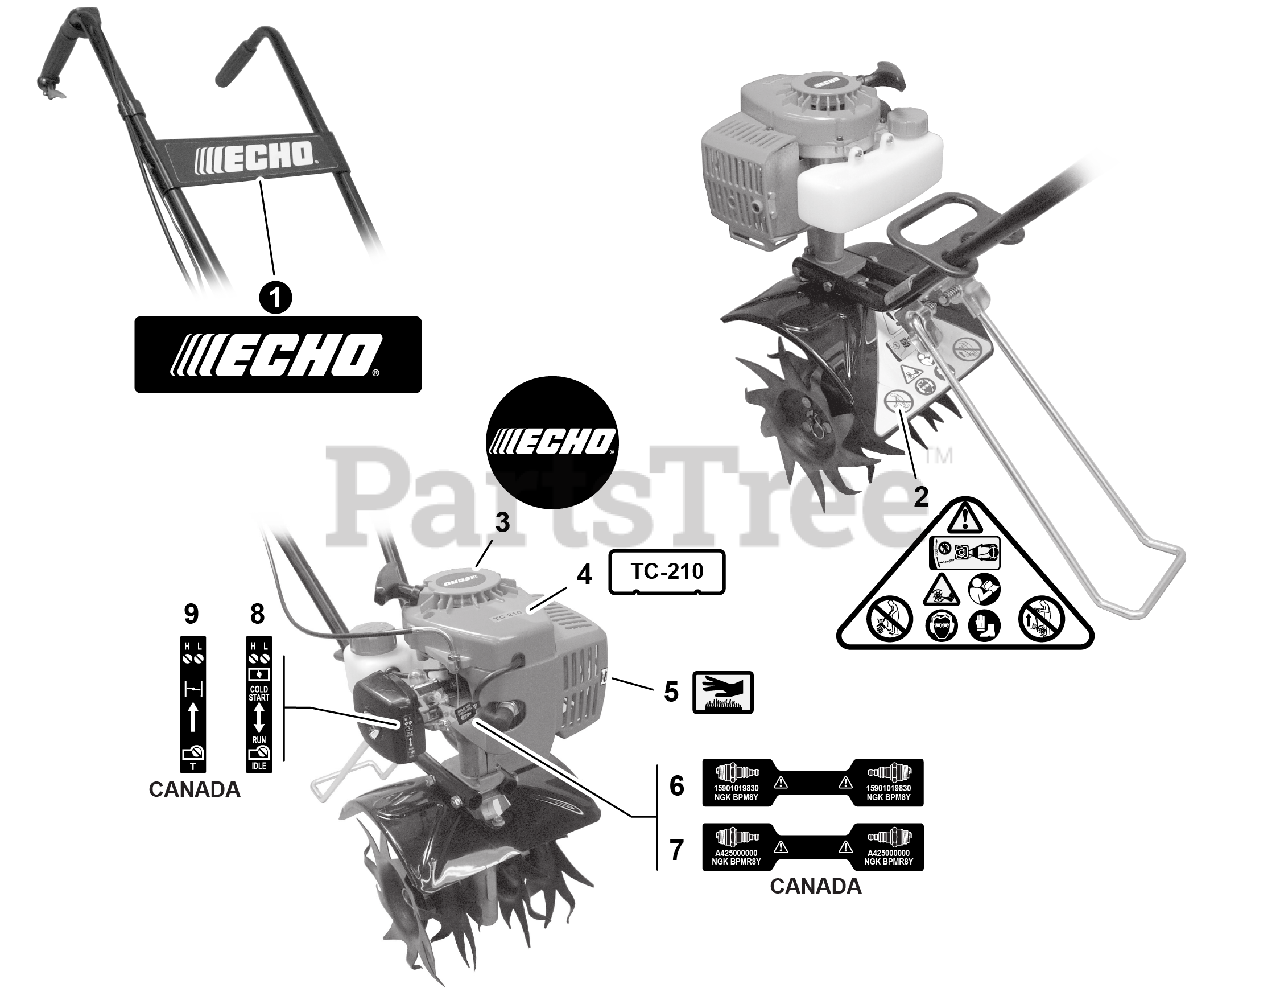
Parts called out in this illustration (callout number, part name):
1	LABEL, ECHO
2	LABEL, CAUTION
3	LABEL, ECHO
4	LABEL, MODEL
5	LABEL, CAUTION - HOT
6	LABEL, SPARK PLUG - BPM8Y
7	LABEL, SPARK PLUG - BPMR8Y
8	LABEL, CHOKE
9	LABEL, CHOKE
